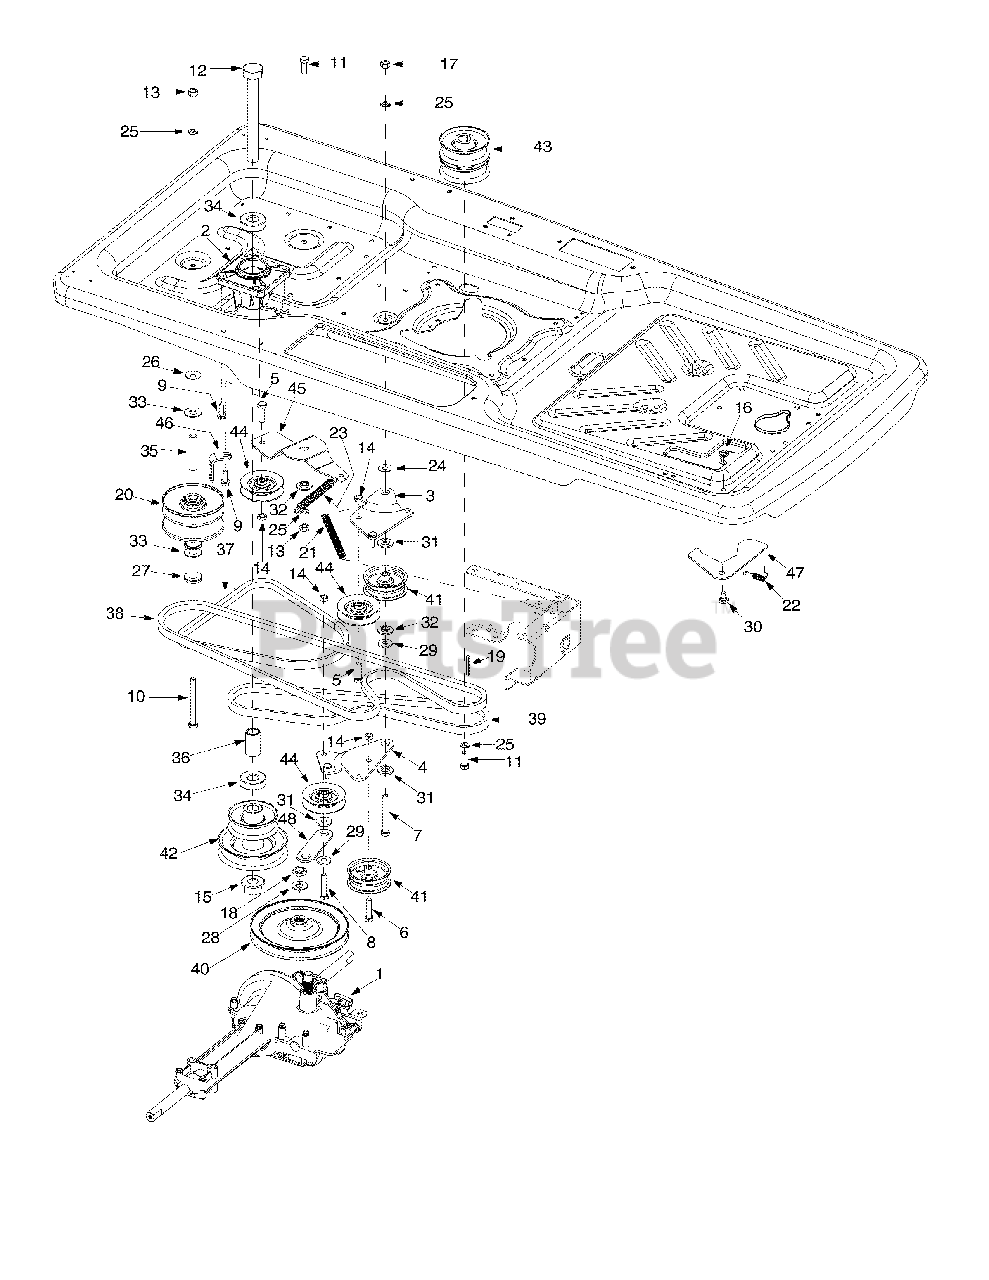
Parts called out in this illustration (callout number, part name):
1	Transmission Assembly
2	Spindle Housing
3	Idler Bracket Assembly
4	Idler Bracket Assembly
5	Hex Bolt 3/8-24 x 1.25"
6	Hex Bolt 3/8-24 x 1.50"
7	Hex Bolt 3/8-16 x 3.0"
8	Hex Bolt 3/8-24 x 1.75"
9	TT Screw 5/16-18 x 0.875"
10	Hex Screw 3/8-24 x 3.75"
11	Hex Screw 3/8-24 x 1.0"
12	Hex Screw M20 x 2.5:180
13	Hex Nut 3/8-24
14	Jam Lock Nut 3/8-24
15	Hex Flange Nut M20 x 2.5
16	Flange Lock Nut 5/16-18
17	Hex Nut 3/8-16
18	Jam Nut 9/16-18
19	Key
20	Variable Speed Pulley Assembly
21	Extension Spring
22	Extension Spring
23	Extension Spring
24	Flat Washer .406 x 1.0 x .030
25	Lock Washer 3/8
26	Bell Washer .39 x 1.13 x .062
27	Flat Washer 3/8 x 1.25"
28	Bell Washer .567 x 1.125 x .06
29	Flat Washer .406 x 1.0 x .105
30	Shoulder Screw
31	Shoulder Spacer
32	Shoulder Spacer
33	Thrust Bearing
34	Ball Bearing
35	Sleeve Spacer
36	Spacer
37	Belt: V Type
38	Belt: V Type
39	Belt: V Type
40	Transmission Pulley
41	Flat Idler Pulley
42	Jack Pulley: Double
43	Engine Pulley: Double
44	Idler Pulley
45	Idler Bracket: Variable Speed
46	Cable Bracket
47	Bracket: Lock: Pedal
48	Link Bracket
